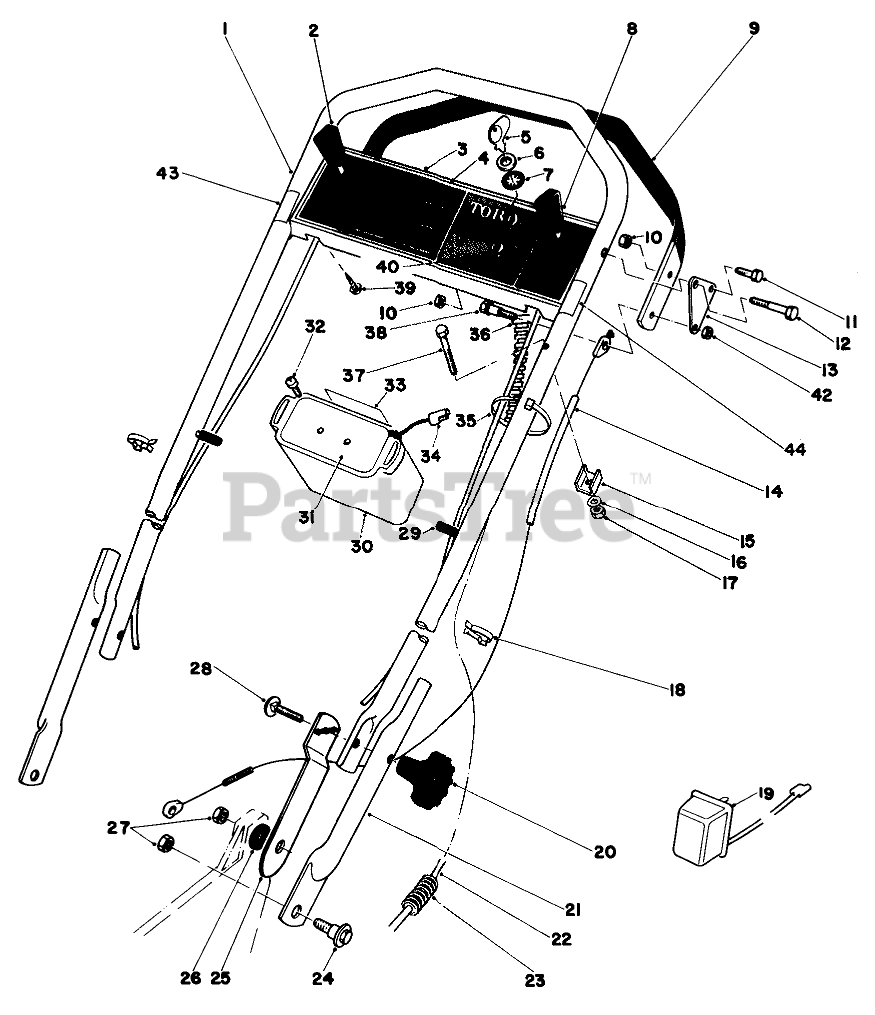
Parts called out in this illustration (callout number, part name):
1	Upper Handle
2	Ground Speed Control
3	Control Panel
4	Decal-Key Lectric
5	Key
6	NUT-HH
7	WASHER-TOOTH, INTERNAL
8	Throttle Control
9	DEMAND HANDLE ASM
10	NUT-LOCK, CONE
11	SCREW-HH
12	BOLT-SHOULDER
13	Bracket Demand
14	DEMAND HAND CABLE
15	CLAMP-CABLE
16	WASHER-FLAT
17	NUT-LOCK, NI
18	BOWDEN CLIP
19	Charger
21	LOWER HANDLE
22	Wiring Harness
23	Cover-Wiring Harness
24	SCREW-SHOULDER
25	Handle Latch L.H.
26	SPACER
27	Nut
28	SCREW-CARR
29	CAP-VINYL
30	Battery Case
31	BATTERY COVER
33	Decal
34	Plug & Wire
35	TIE-CABLE
36	RING FITTING
37	SCREW-HH
38	SHOULDER BOLT
39	SCREW-HWHTF
40	Starter Switch (Incl. Ref. #5-7)
42	NUT-HEX, SIDE DEFORM
43	Decal-Control Shift (French & Dutch)
44	Decal-Throttle Control (French & Dutch)
